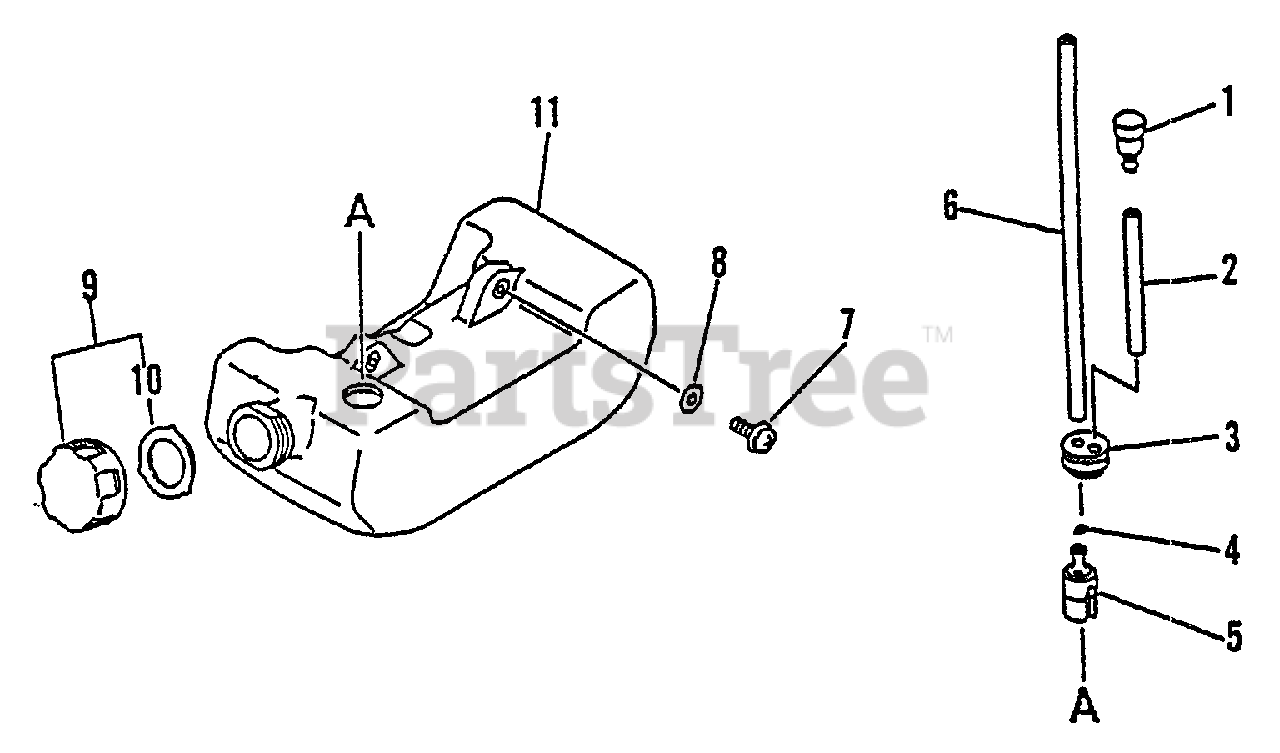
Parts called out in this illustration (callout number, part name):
1	VENT, FUEL TANK
2	PIPE - 3X5X70 -- BLACK
3	GROMMET
4	CLIP - 6
5	FILTER, FUEL
6	PIPE - 3X5X180 -- BLACK
7	SCREW - 5X16
8	WASHER - 5
9	CAP ASSY
10	GASKET, CAP
11	TANK, FUEL
